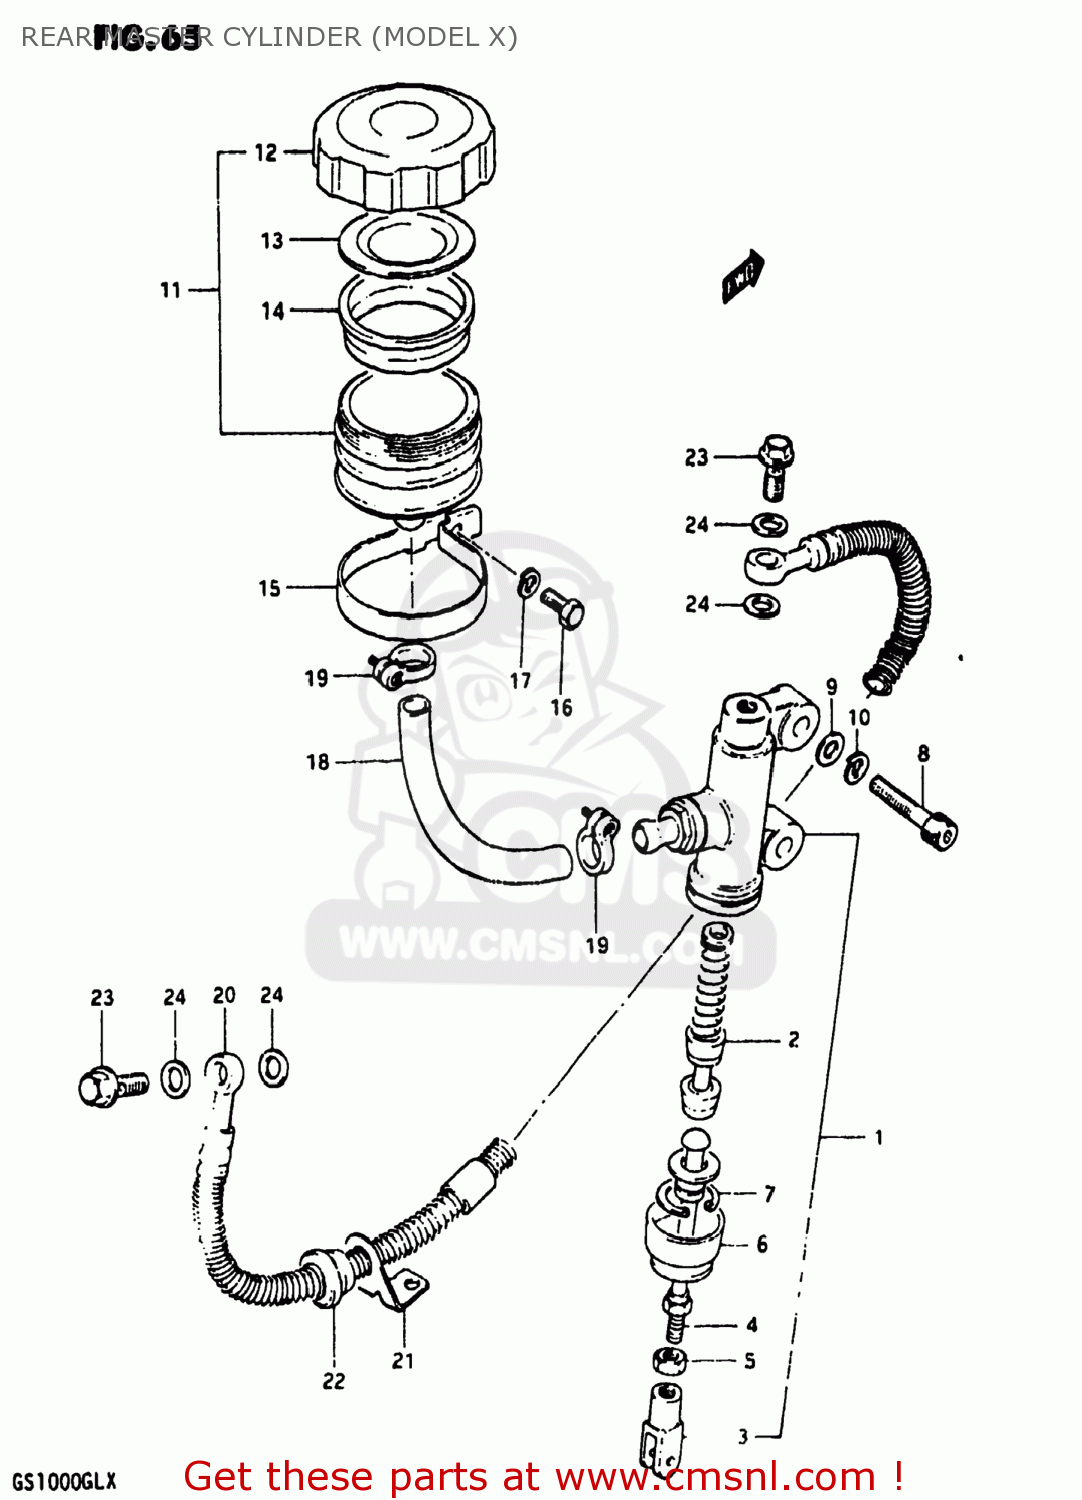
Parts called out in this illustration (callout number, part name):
1	CYLINDER ASSEMBLY,REAR MASTER
2	PISTON/CUP SET
3	YOKE
4	ROD,REAR MASTER CYLINDER
5	NUT
6	BOOT
7	CIRCLIP
8	BOLT
9	WASHER
10	WASHER,LOCK,8.
11	TANK ASSEMBLY,RESERVOIR
12	CAP
13	PLATE,DIAPHRAGM
14	DIAPHRAGM
15	CLAMP
16	BOLT, UPPER
17	LOCK WASHER
18	HOSE,RESERVOIR TANK
19	CLAMP
20	HOSE,REAR BRAKE
21	GUIDE,BRAKE HOSE
22	GROMMET,BRAKE HOSE GUIDE
23	BOLT,UNION
24	WASHER
